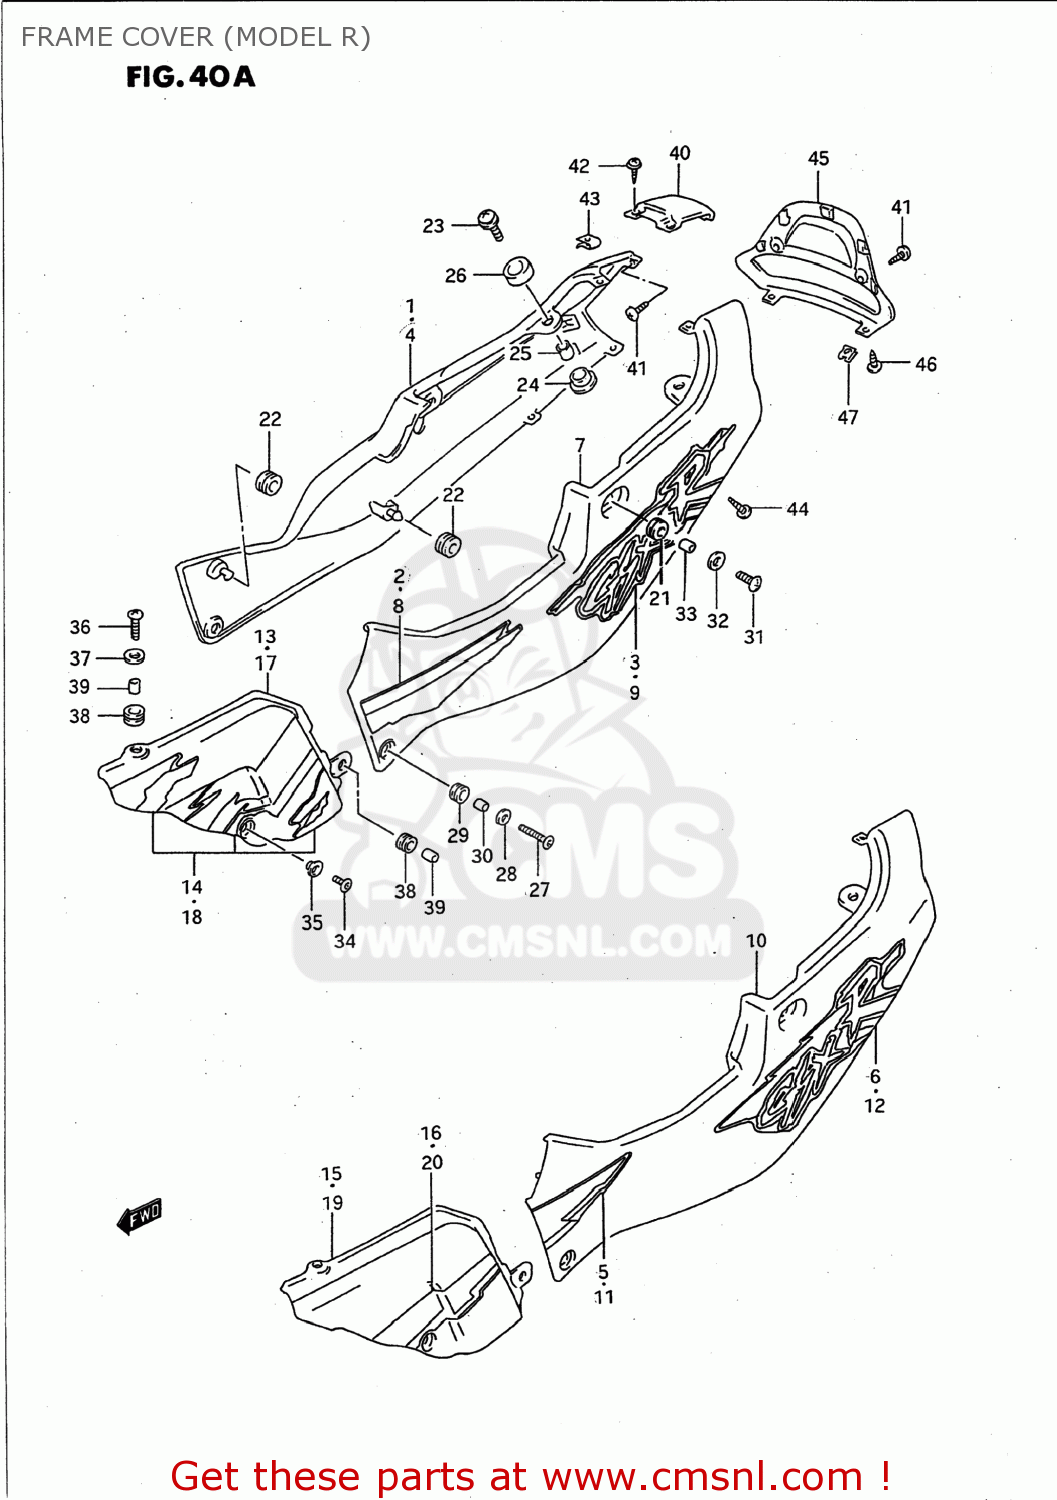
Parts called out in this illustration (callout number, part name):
1	COVER ASSEMBLY,FRAME,RIGHT
2	TAPE,FRAME COVER STRIPE,R
3	EMBLEM,FRAME COVER,R
4	COVER ASSEMBLY,FRAME,RIGHT
5	TAPE,FRAME COVER STRIPE
6	EMBLEM,FRAME COVER,R
7	COVER ASSY,FRAME,L(WHITE)
8	TAPE,FRAME COVER STRIPE,L
9	EMBLEM,FRAME COVER,LEFT
10	COVER ASSEMBLY,FRAME,LEFT
11	TAPE,FRAME COVER STRIPE
12	EMBLEM,FRAME COVER,LEFT
13	COVER ASSY,FRAME BODY,R
14	TAPE SET,FRAME COVER B
15	COVER ASSEMBLY,FRAME BODY
16	TAPE,FRAME COVER BODY,R
17	COVER ASSY,FRAME BODY,L
18	TAPE SET,FRAME COVER B
19	COVER ASSY,FRAME BODY,L
20	TAPE,FRAME COVER BODY,L
21	CUSHION
22	CUSHION
23	SCREW(6X30)
24	CUSHION,FRAME COVER LWR
25	SPACER (6,8X10X9.4)
26	CUSHION,TAIL COVER UPR
27	SCREW(6X30)
28	WASHER
29	CUSHION
30	SPACER (6.1X9X9)
31	SCREW(6X20)
32	WASHER(6.5X22X1.6)
33	SPACER (6.3X9.1X6.7)
34	SCREW(5X14)
35	WASHER
36	SCREW
37	WASHER (6.5X18X1.6)
38	CUSHION
39	SPACER (6.1X9X9)
40	COVER ASSY,FRAME CTR
41	SCREW(5X12)
42	SCREW
43	NUT
44	SCREW
45	COVER,FRAME RR
46	SCREW(5X12)
47	NUT
